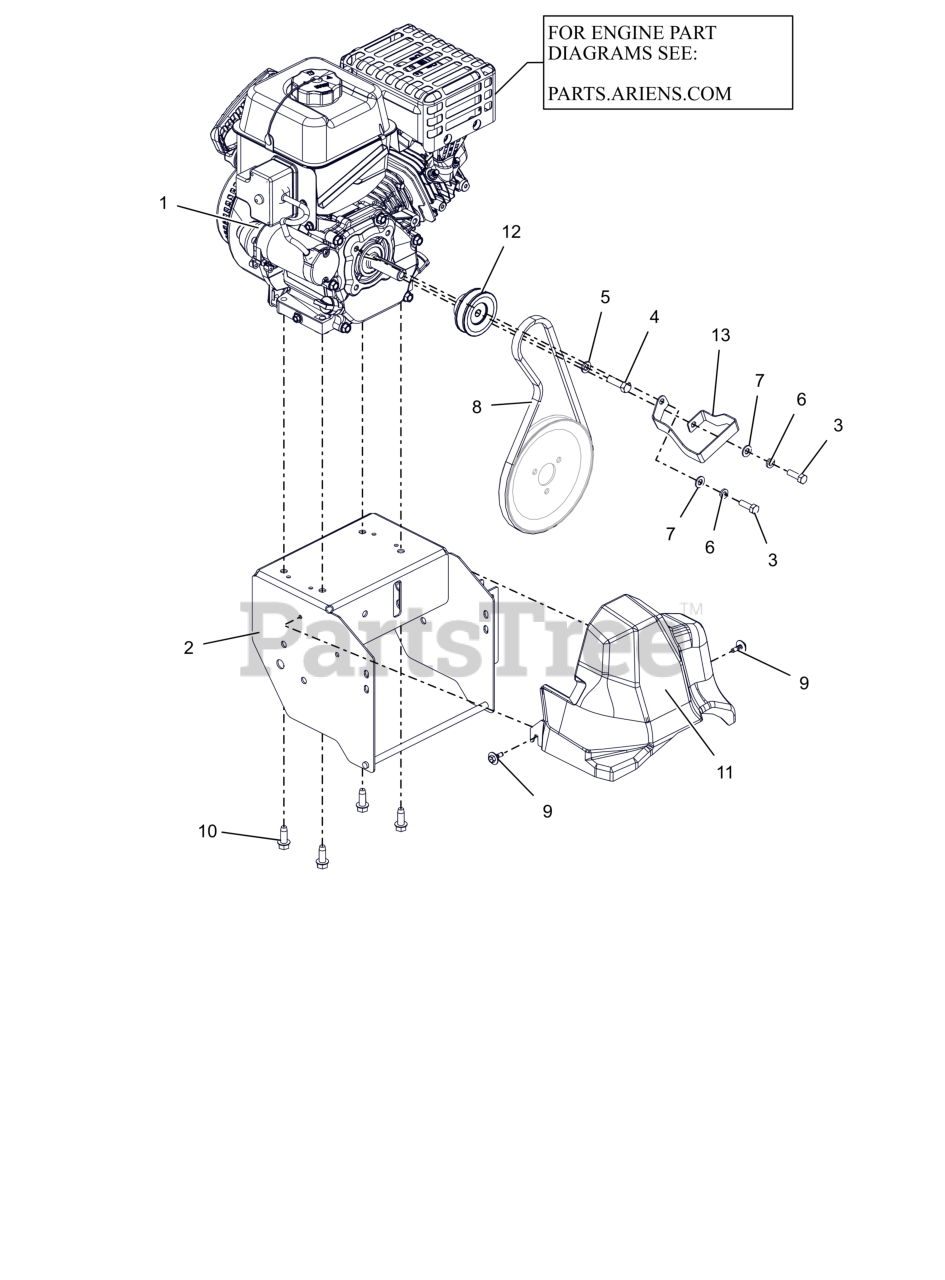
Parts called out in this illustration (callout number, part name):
1	Engine, AX179 120v Gen II
2	WLDMT, FRAME (ORANGE)
3	BLT, HEX 0.3125-24X1 G5 ZCC
4	BLT, HEX .38-24X1.25 G5 ZCC
5	WSHR,LK-REG .375X.094 ZCC
6	WSHR, LK-HVY .312X.097 ZCC
7	WSHR,FLT .344X.688X.065 ZCC
8	V-BELT, 4L RAW EDGE CNA EPDM
9	SCR-TAP .25-20X.5 CAPTIVE
10	SCR-TAP .38-16X1.00 HWH TR ZCC
11	COVER, BELT - CROSSOVER
12	SHEAVE, ENGINE SINGLE GRV
13	FINGER, BELT
